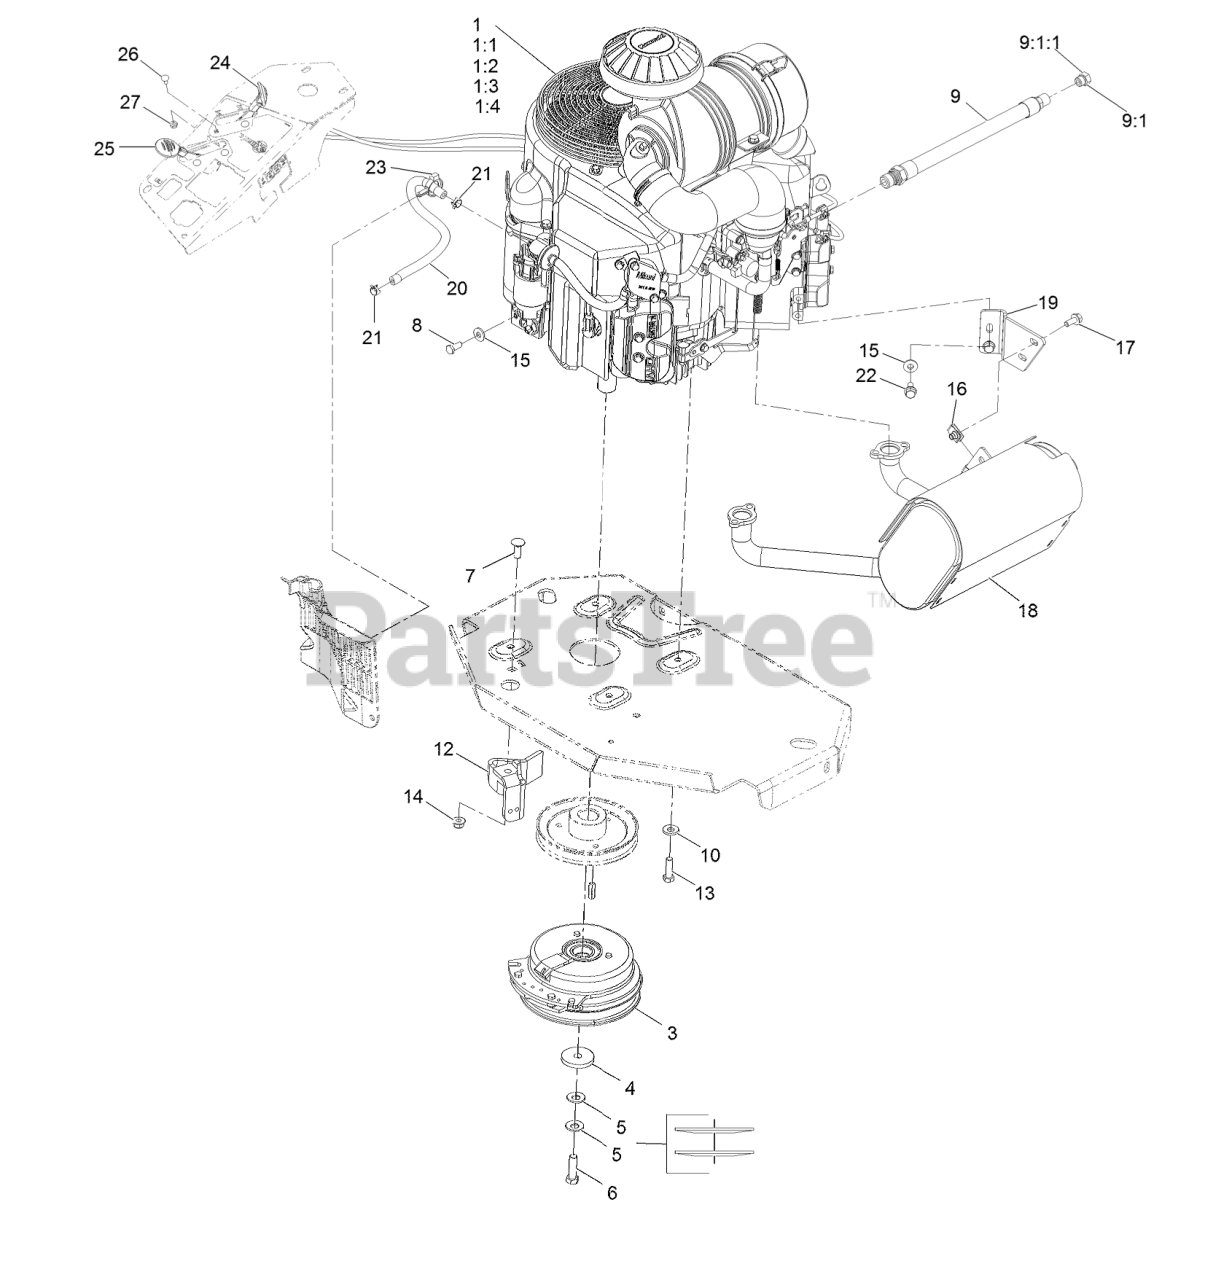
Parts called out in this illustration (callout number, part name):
1:1	Kawasaki 49065-2078 Engine Oil Filter
1:2	Kawasaki 49019-7001 Fuel Filter
1:3	Kawasaki 11013-7039 Safety Filter
1:4	Kawasaki 11013-7038 Air Filter
3	CLUTCH KIT
4	WASHER-CLUTCH
5	WASHER-SPRING
6	SCREW-HH 7/16-20 X 1 1/2 W/LOCTITE
7	SCREW-CARR
8	SCREW-HH
9	ENGINE OIL DRAIN HOSE ASM
9:1	PLUG-HH
9:1:1	O-RING
10	WASHER-BELLEVILLE
12	CLUTCH-ANCHOR
13	SCREW-HH
14	NUT-HF, NI
15	WASHER-SPRING
17	SCREW-HHF
18	MUFFLER
19	BRACKET-MUFFLER
20	HOSE-FUEL
21	CLAMP-HOSE
22	SCREW-HHF
23	CLAMP-HOSE
